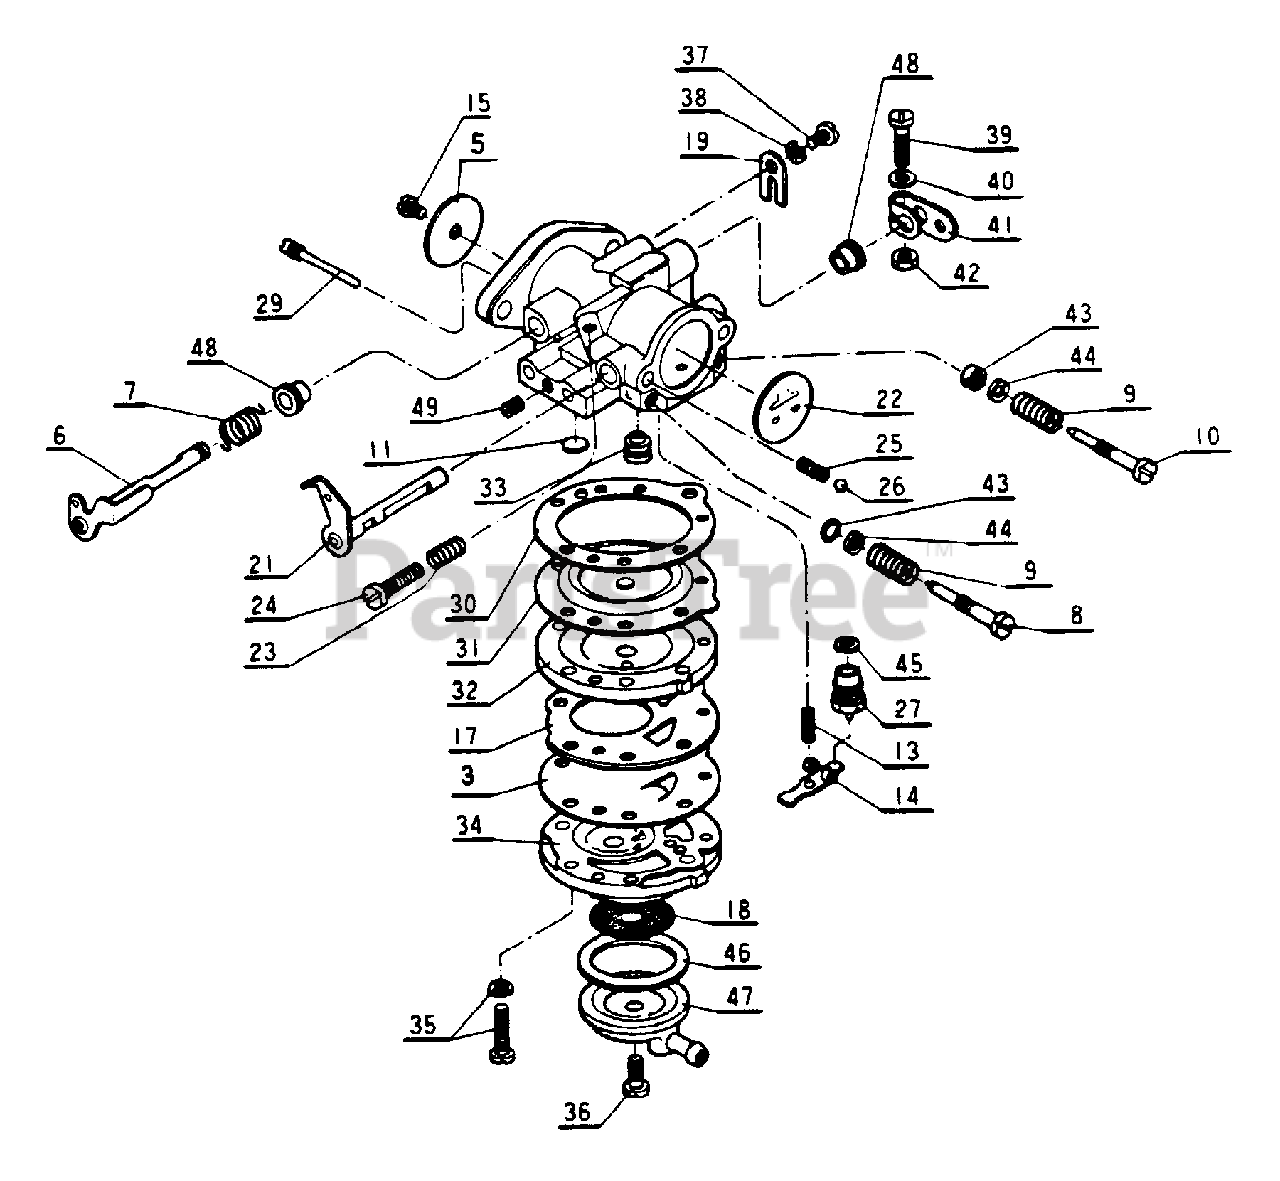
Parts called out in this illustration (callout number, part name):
3	DIAPHRAGM, PUMP
5	VALVE, THROTTLE
6	SHAFT, THROTTLE
7	SPRING, RETURN
8	SCREW, IDLE ADJUST
9	SCREW, IDLE ADJUST
10	SCREW, MAIN ADJUST
11	PLUG, WELCH - LARGE
13	SPRING, METERING LEVER
14	LEVER, METERING
15	SCREW
17	GASKET, PUMP
18	FILTER, FUEL
19	RING, RETAINING
21	SHAFT, CHOKE
22	VALVE, CHOKE
23	SPRING
24	SCREW
25	SPRING, CHOKE SET
26	BALL, CHOKE SET
27	VALVE, INLET NEEDLE
29	SCREW, METERING LEVER PIN
30	GASKET, DIAPHRAGM
31	DIAPHRAGM
32	COVER, DIAPHRAGM
33	VALVE, CHECK
34	BASE, PURGE
35	SCREW
36	SCREW
37	SCREW
38	WASHER
39	SCREW
40	WASHER
41	LEVER, THROTTLE
42	NUT
43	PACKING
44	WASHER
45	GASKET, NEEDLE VALVE
46	SEAL
47	COVER, FUEL FILTER
